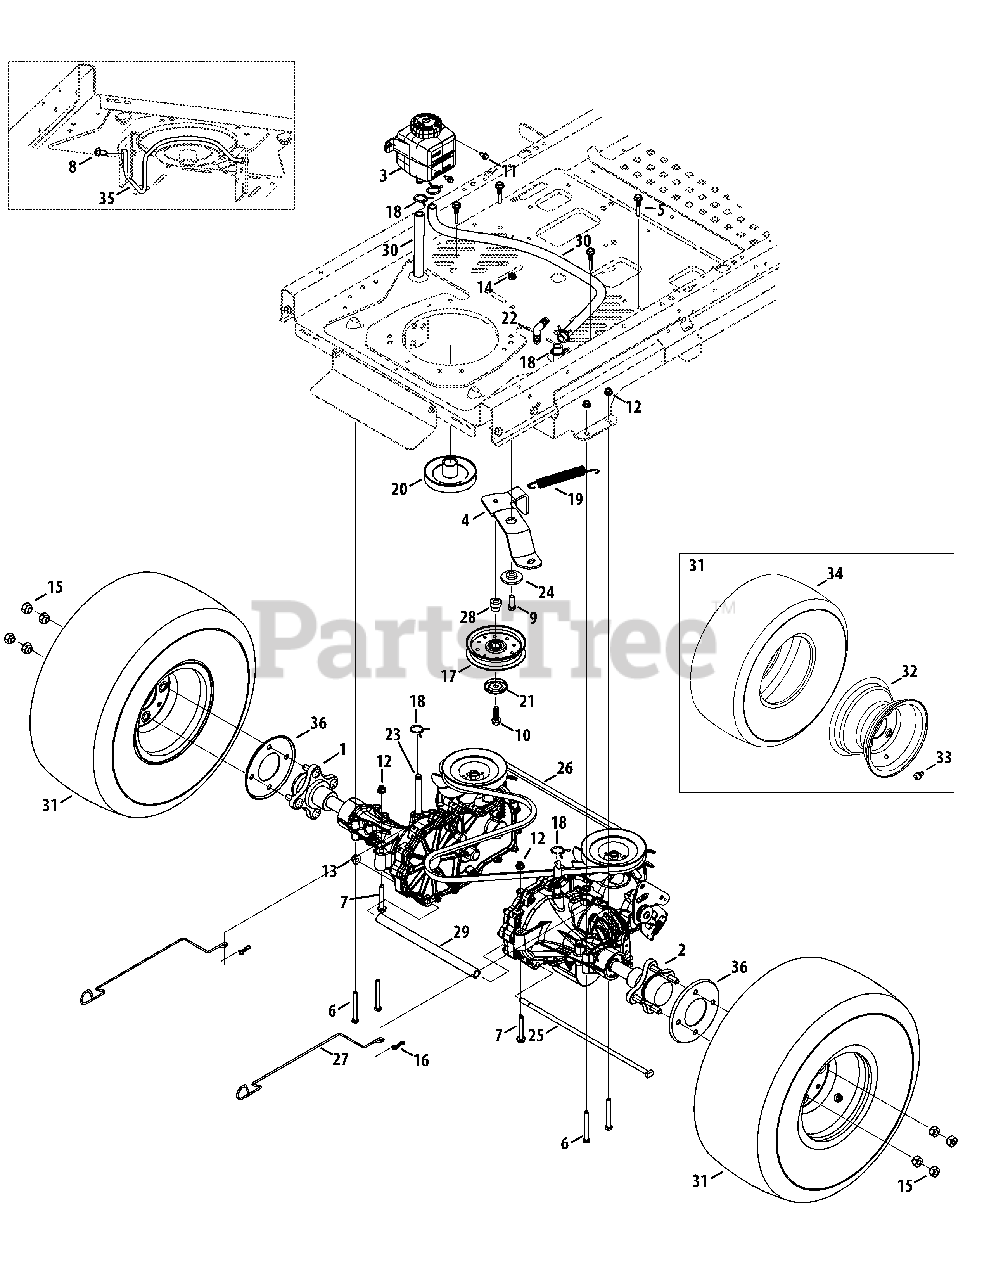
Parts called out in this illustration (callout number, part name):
1	Transmission Assembly, LH
2	Transmission Assembly, RH
3	Expansion Tank Assembly
4	Idler Bracket
5	Keeper Rod, .25 x 1.535
6	Hex Screw, 5/16-18 x 2.75
7	Screw-HHCS 5/16-18 x 2.25
8	SCREW 5/16-18 x .750
9	Hex Screw, 3/8-16 x 1.00
10	Hex Washer Screw, 3/8-16 x 1.250
11	Hex Washer Screw, 1/4-20 x .625
12	Flange Lock Nut, 5/16-18
13	Flange Lock Nut, 3/8-16
14	Jam Lock Nut, 3/8-16
15	Lug Nut, 7/16-14
16	Bow-Tie Cotter Pin
17	Idler Pulley, 4.25 Dia.
18	Hose Clamp, ..75 Adj
19	Extension Spring, .75 Dia. x 6.02
20	Engine Pulley
21	Pulley Cap
23	Fitting, 9/16, Barb
24	Shoulder Spacer, .884 x .190
25	Rod, .337 Dia. x 14.75 LG
26	Belt, A-Type x 67.0
27	Bypass Rod
28	Shoulder Spacer
29	Spacer, .75 OD x 11.31 LG
30	Fuel Hose, 1/2 ID
31	Complete Wheel, 22 x 13-6.5
32	Rim Only
33	Valve Tubeless
35	Engine Keeper Rod
36	Reinforcement Plate
